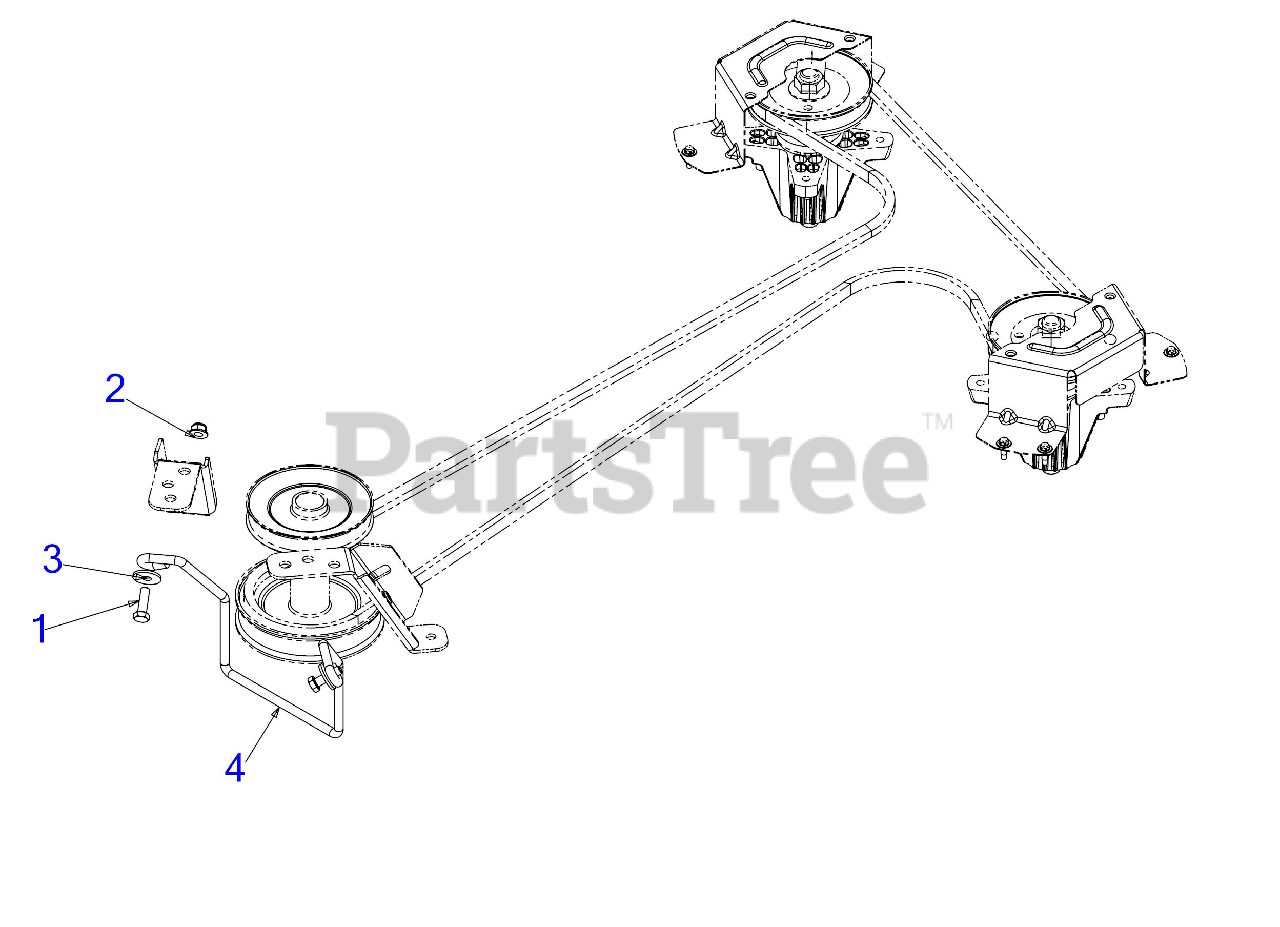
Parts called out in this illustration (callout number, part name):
1	SCREW 5/16-18 x 1.0 GR5
2	FLANGE LOCK NUT 5/16-18
3	FLAT WASHER 1.0 OD:.331 ID
4	BELT KEEPER ROD
